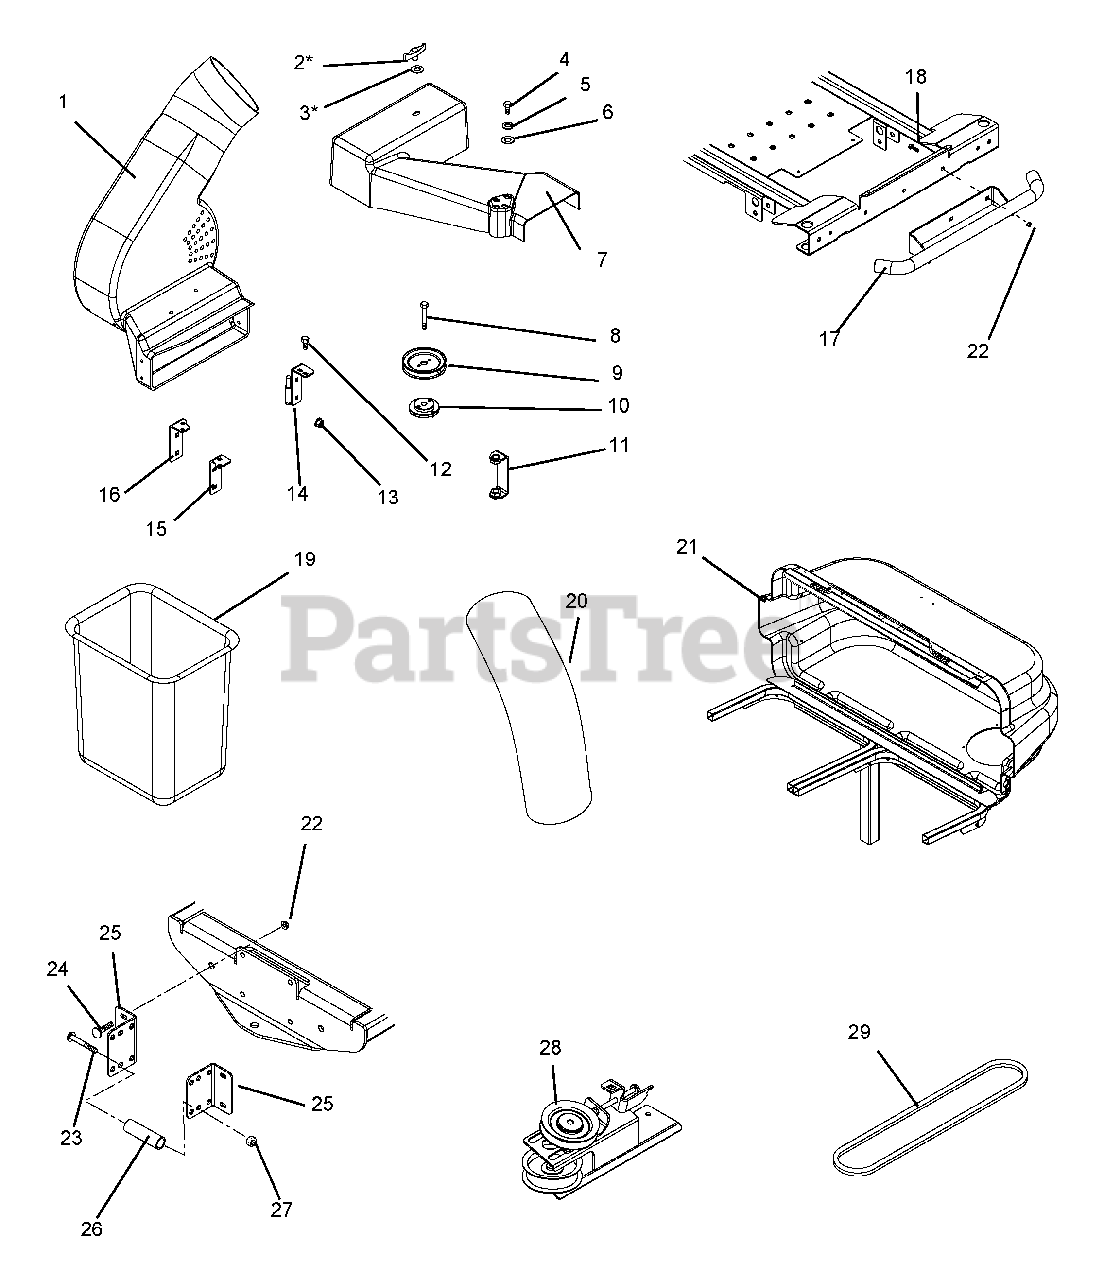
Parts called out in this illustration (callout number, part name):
1	Blower Assembly
2	Wing Knob
3	3/8" x 1-1/2" Washer
4	3/8" x 3/4' Hex Bolt
5	3/8" Lock Washer
6	7/16" x 1" Flat Washer
7	Belt Cover
8	3/8" x 1-3/4" Hex Bolt
9	3-Inch Sheave
9	4-Inch Sheave
10	Sheave Adapter
11	Cover Spacer
12	1/4" x 3/4" Hex Bolt
13	1/4" Top Lock Flange Nut
14	Rear Mount Weldment Bracket
15	Front Bracket
16	Front Mount Weldment Bracket
17	Front Bumper
18	3/8" x 1" Hex Bolt
19	Grass Bagger Basket
20	Hose
21	Cover Assembly
22	3/8" Flange Nyloc Nut
23	1/2" x 3" Hex Bolt
24	3/8" x 1-1/4" Round Head Square Neck Bolt
25	Bagger Mount Bracket
26	Pivot Spacer
27	1/2" Top Lock Flange Nut
28	Idler Assembly
29	V-Belt
